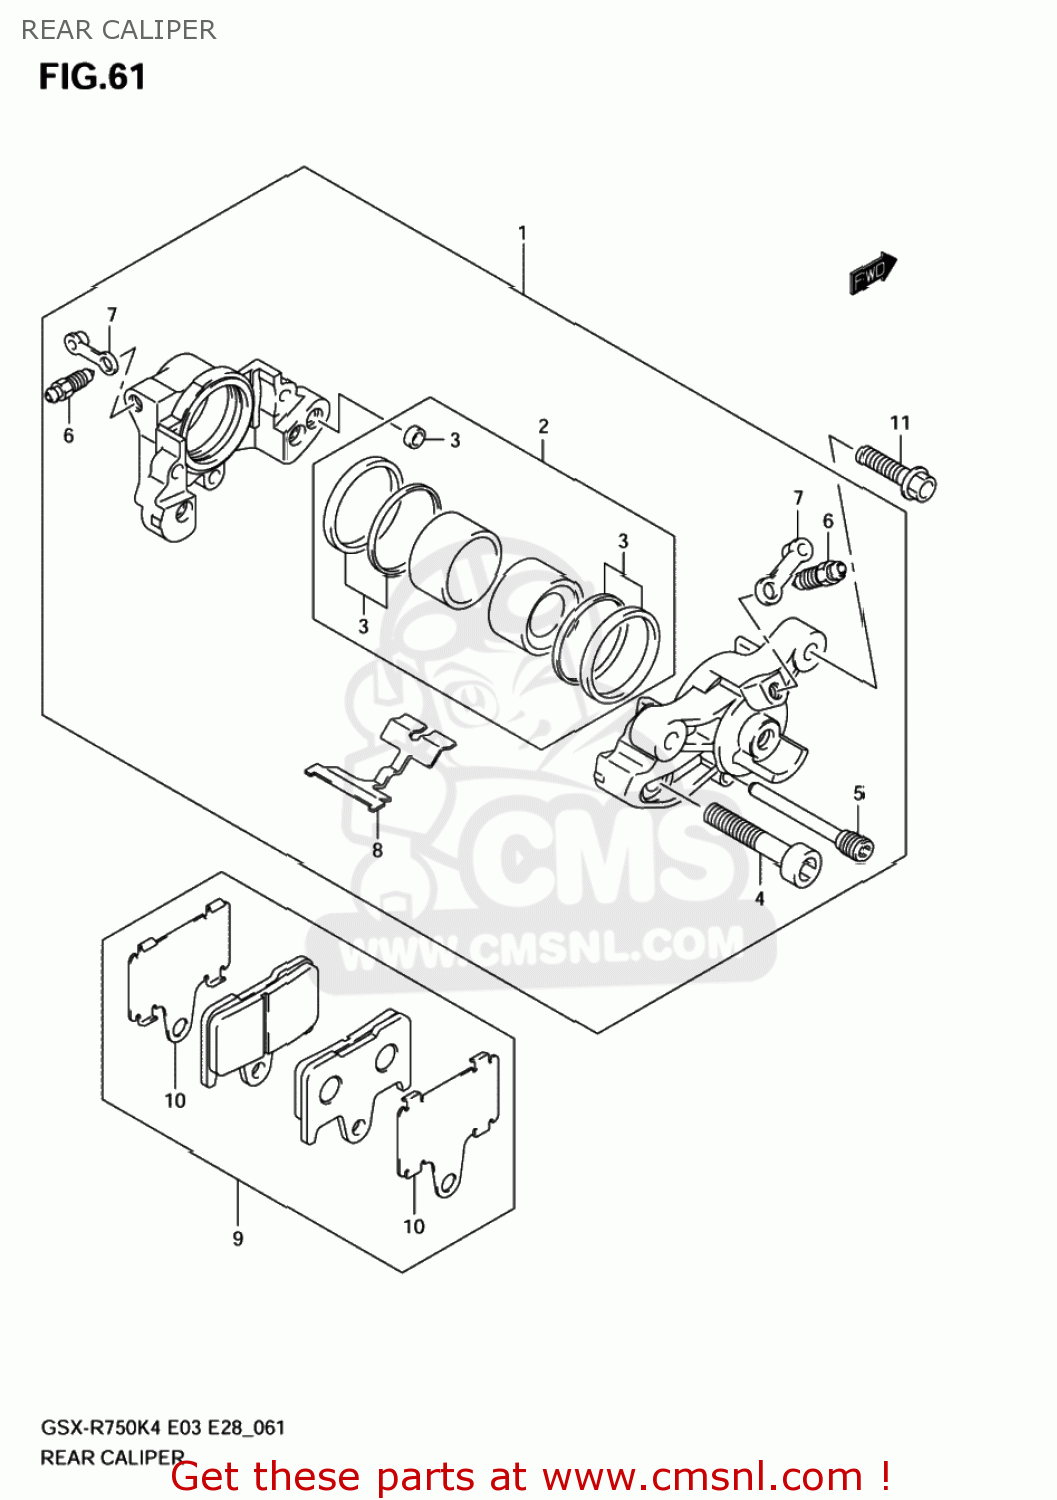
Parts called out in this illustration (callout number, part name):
1	CALIPER ASSY,RR
2	PISTON SET
3	SEAL SET,PISTON
4	BOLT,HOUSING
5	PIN,PAD
6	BLEEDER
7	CAP,BLEEDER
8	SPRING,PAD
9	PAD & SHIM SET (NAS)
10	SHIM,PAD
11	BOLT(8X28)
